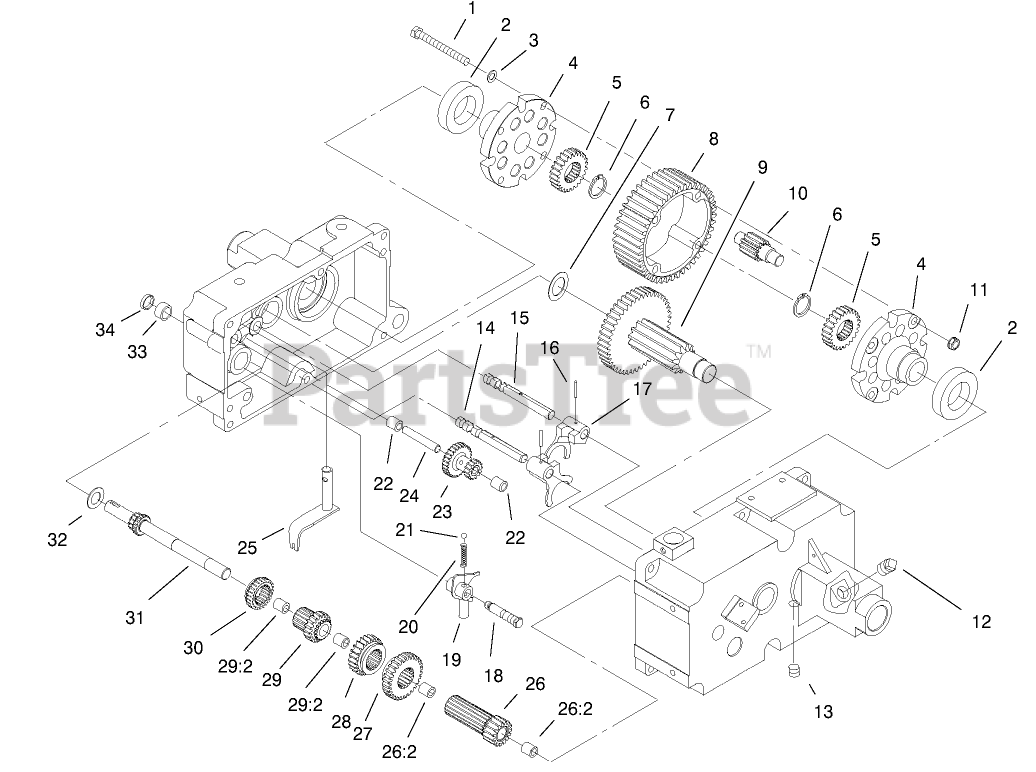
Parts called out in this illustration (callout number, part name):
2	BEARING-BALL
3	WASHER
4	END CAP-DIFFERENTIAL
5	GEAR-AXLE DIFFERENTIAL
6	RING-SNAP
7	WASHER-THRUST
8	GEAR-DIFFERENTIAL RING, 43T
9	GEAR ASM
10	GEAR-PINION, 11T
11	NUT-HEX
12	PLUG-PIPE, SQH
13	PLUG-PIPE
14	RAIL-SHIFT
15	RAIL-REAR SHIFT
16	PIN-ROLL
17	FORK-SHIFT
18	BOLT-DETENT
20	SPRING-SHIFT STOP
21	BALL-DETENT
22	BEARING-NEEDLE
24	GEAR-SHAFT REDUCTION
25	SHIFT ASM
26	GEAR
26:2	BEARING-NEEDLE
27	GEAR-LOW AND REVERSE
28	GEAR-HI AND 2ND
29	GEAR
29:2	BEARING-NEEDLE
30	GEAR-SLIDING
31	SHAFT-INPUT
32	WASHER-THRUST
33	BEARING-NEEDLE
34	SEAL-OIL
